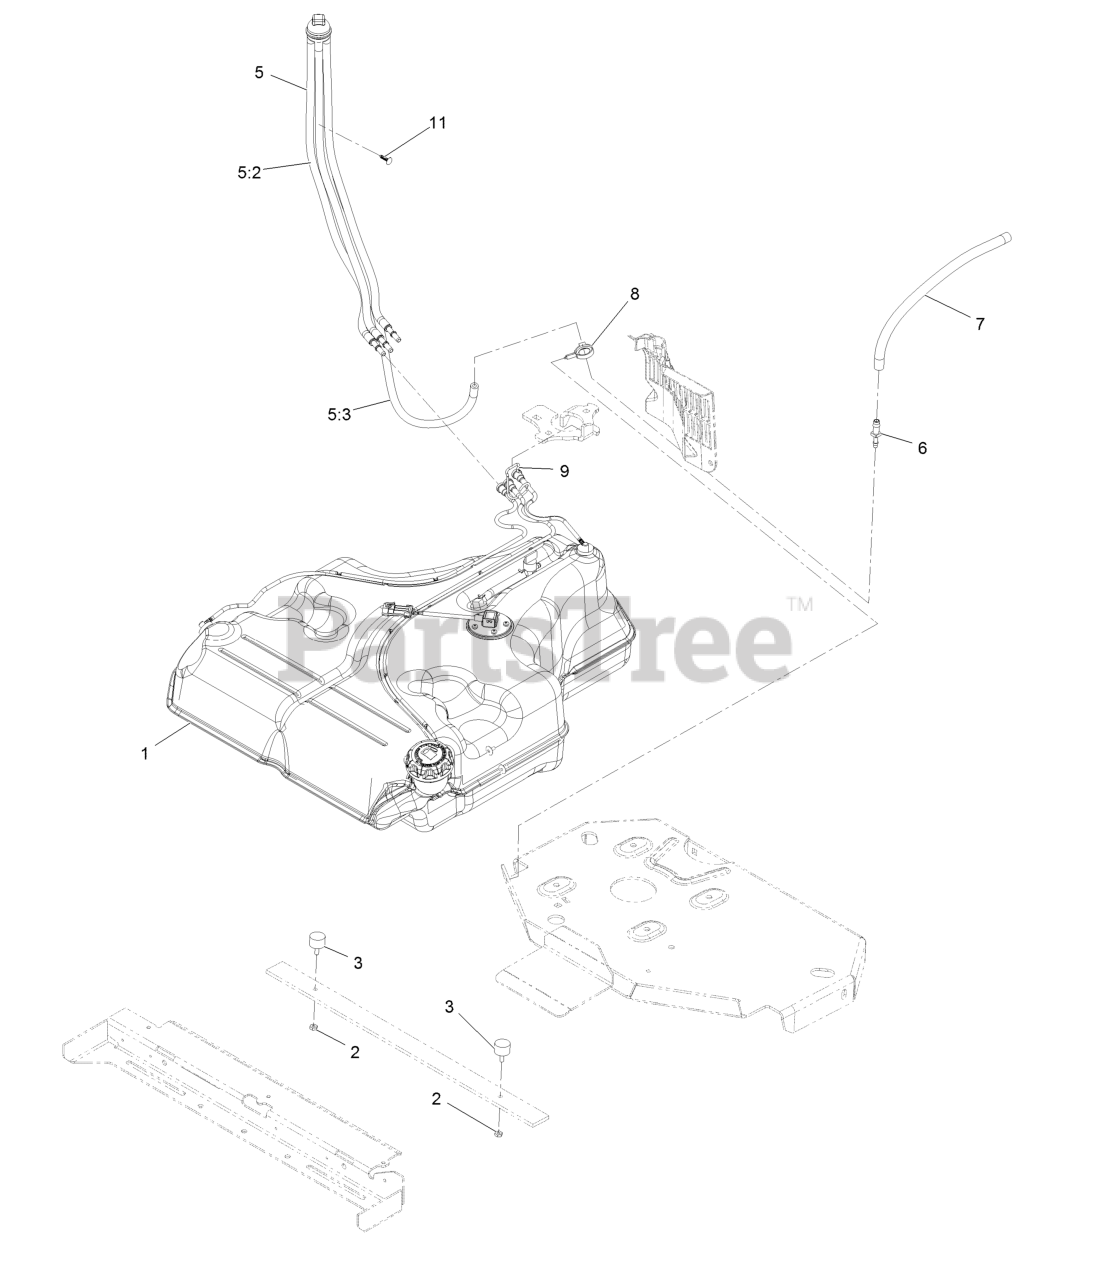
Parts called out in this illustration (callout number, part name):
1	FUEL TANK ASM
2	NUT-JAM
5	FUEL MANIFOLD VENT ASM
5:2	HOSE-FUEL
5:3	HOSE-FUEL
6	FITTING-STRAIGHT
7	HOSE-FUEL
8	CLAMP-HOSE
9	RETAINER-LINE, VAPOR
11	PLUG-PLASTIC
